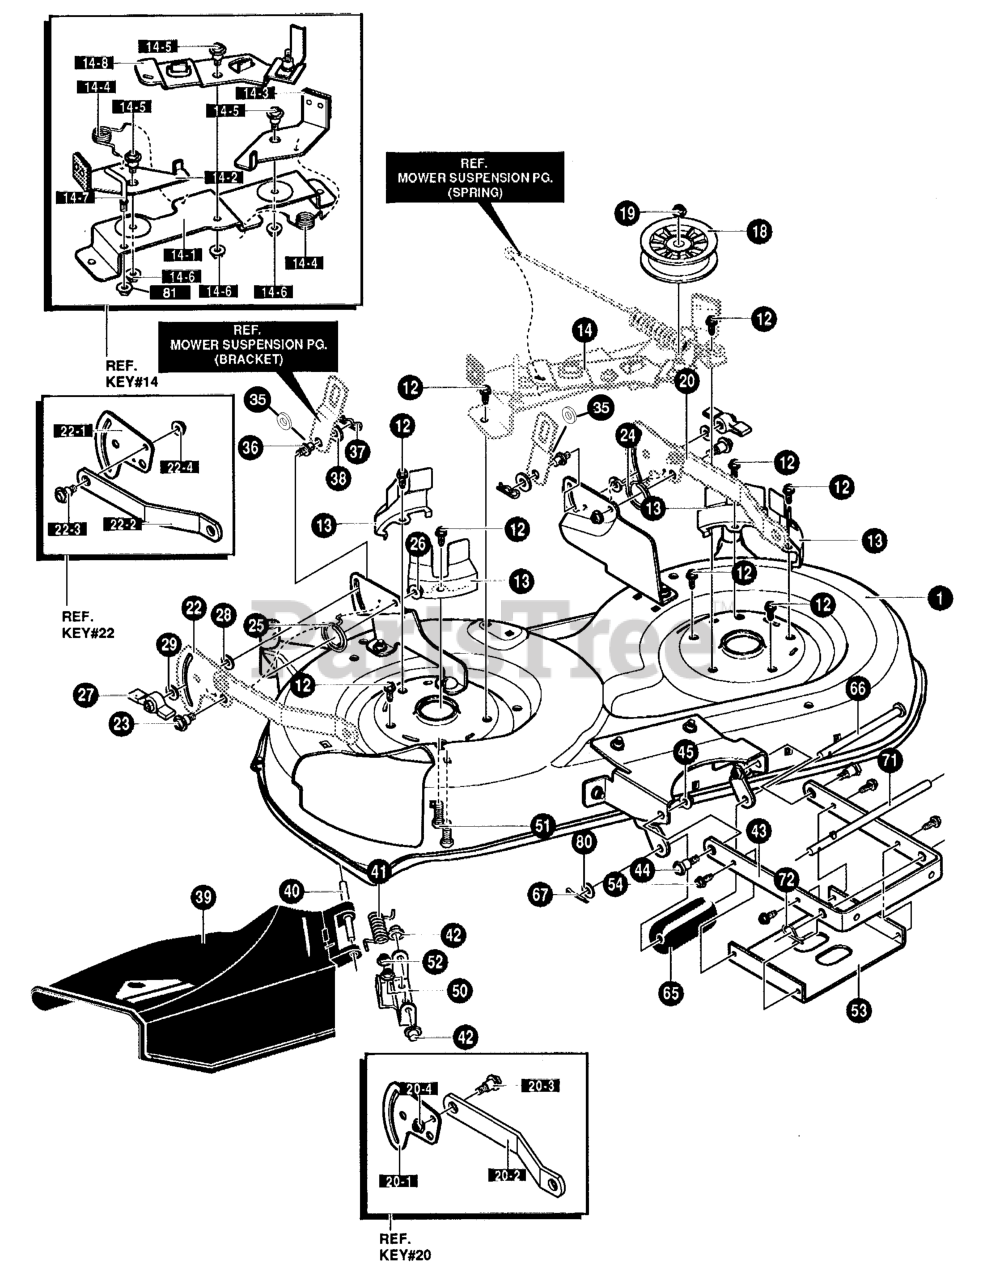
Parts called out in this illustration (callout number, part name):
1	ASSY 42" MOWER DECK
12	SCREW, 3/8- 1 6X1 .25
13	COVER, SEGMENT BELT GUIDE
14-1	BRACKET, BRAKE MT
14-2	ASSY BRAKE RH
14-3	ASSY BRAKE RH
14-4	TORSION SPRING
14-5	BOLT.50X.75
14-6	NUT, 3/8-16
14-7	SCREW GUIDE
14-8	ASSY IDLER ARM
18	PULLEY, IDLER
19	NUT, 3/8-16
20	PLATE, REAR SUS. BRKT. LH
20-1	PLATE - SUSPENSION
20-2	SUSPENSION BRKT REAR
20-3	BOLT, SHOULDER 3/8-16
20-4	NUT, 3/8-16
22	PLATE, REAR SUS. BRKT. RH
22-1	PLATE - SUSPENSION
22-2	SUSPENSION BRKT REAR
22-3	BOLT, SHOULDER 3/8-16
22-4	NUT, 3/8-16
23	BOLT, SHOULDER
24	SPRING, TORSION
25	SPRING, TORSION
26	NUT, 3/8-16
28	PAD, FRICTION
35	WASHER, WAVE
36	PIN, HANGER
37	PIN, HAIR
38	WASHER, FLAT
39	CHUTE DEFLECTOR
40	ROD, CHUTE DEFLECTOR
41	SPRING, TORSION
42	NUT, PUSH CAP
43	BRACKET, FRT SUSPENSION
44	BOLT, SHOULDER
45	NUT, 3/8-16
50	BRACKET, CHUTE
51	BOLT, 5/16-18X.63
52	NUT, 5/16-18
53	STIFFENER NLT
54	SCREW, 5/16-18 x 0.75
66	ROD, SUPPORT
67	PIN, COTTER
71	ROD HANGER
72	HAIR PIN
80	FLATWASHER
81	NUT, HEX
